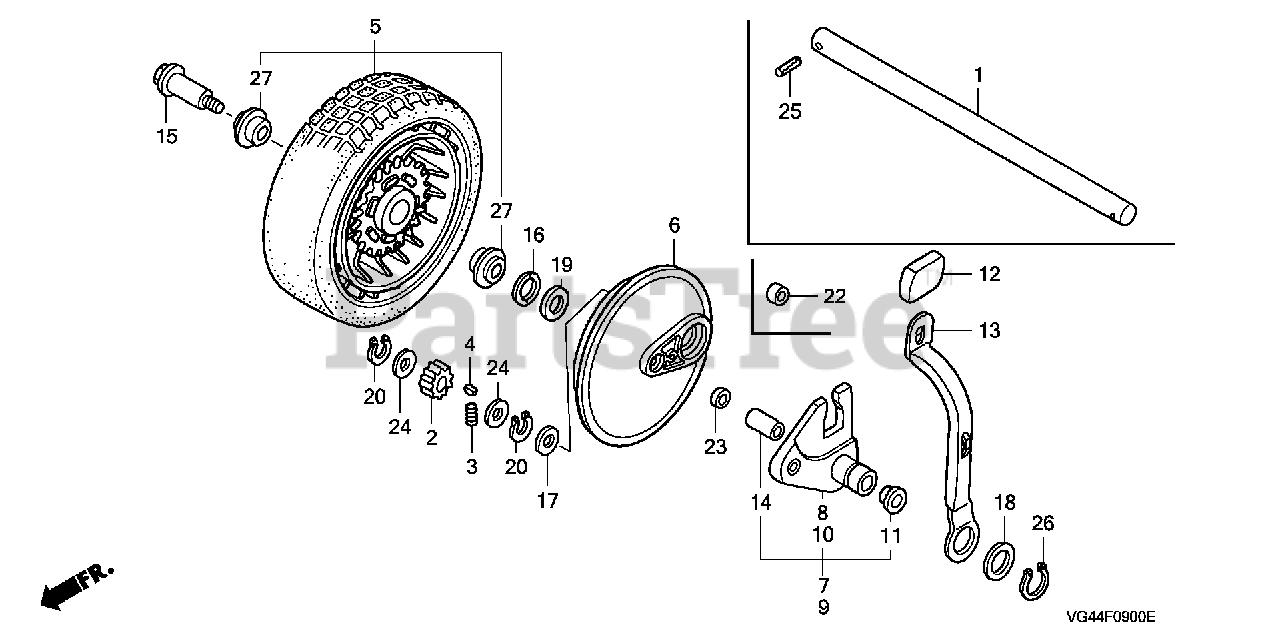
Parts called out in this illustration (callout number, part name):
2	GEAR, PINION (12T)
3	SPRING, RATCHET RETURN
4	KEY, RATCHET
5	WHEEL, RR.
7	ARM, R. RR. ADJUSTING
8	ARM, R. RR. ADJUSTER
9	ARM, L. RR. ADJUSTING
10	ARM, L. RR. ADJUSTER
11	DUST SEAL (12.7MM)
12	GRIP, ADJUSTER
12	GRIP, ADJUSTER *NH105* (MAT BLACK)
13	PLATE, RR. ADJUSTER
14	BUSH, DRIVESHAFT
15	BOLT, RR. WHEEL SHAFT
16	WASHER, WHEEL
17	WASHER, THRUST (13MM)
18	WASHER, FLAT (26X44)
19	WASHER, THRUST (13X27X1)
20	CIRCLIP (OUTER) (12.7MM)
23	COLLAR, THRUST
24	COLLAR, PINION GEAR
26	CIRCLIP (OUTER) (25MM)
27	BEARING, RADIAL BALL
27	BEARING, WHEEL
